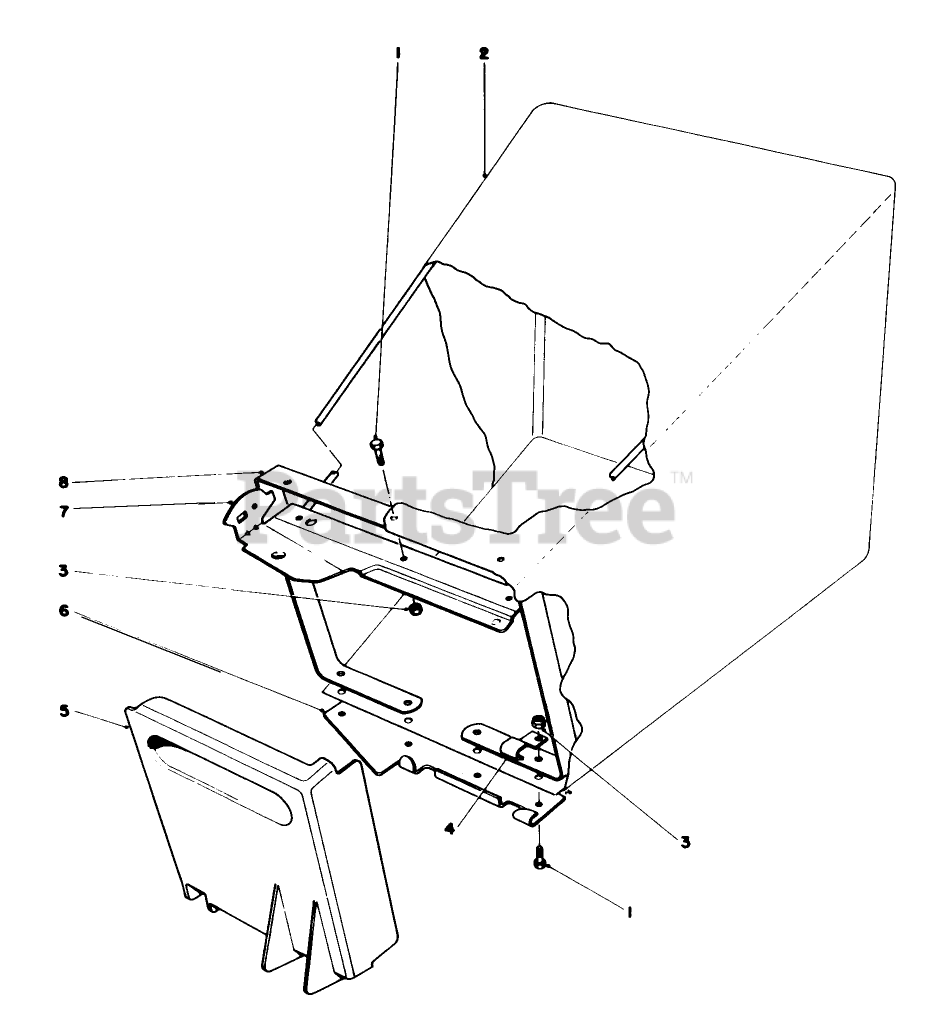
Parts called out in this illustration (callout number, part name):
1	SCREW-HWH
2	Grass Bag Assembly
3	NUT-LOCK, SIDE
4	SUPPORT BRACKET
5	Bag Door
6	DOOR BRACKET
7	BAG FRAME WA
8	LOWER BAG FRAME
